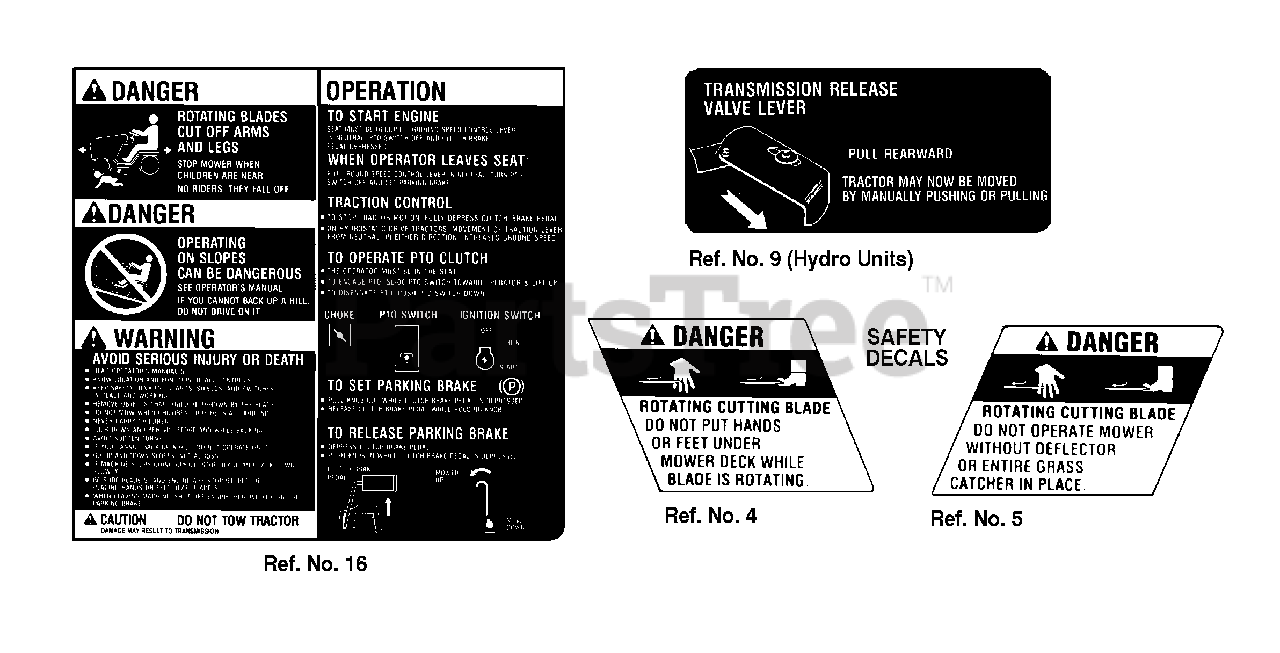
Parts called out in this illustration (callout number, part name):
4	DECAL, Danger (Hand under deck
5	DECAL, Danger (Chute in Place)
9	DECAL, Release Valve
16	DECAL, Operating Instructions
